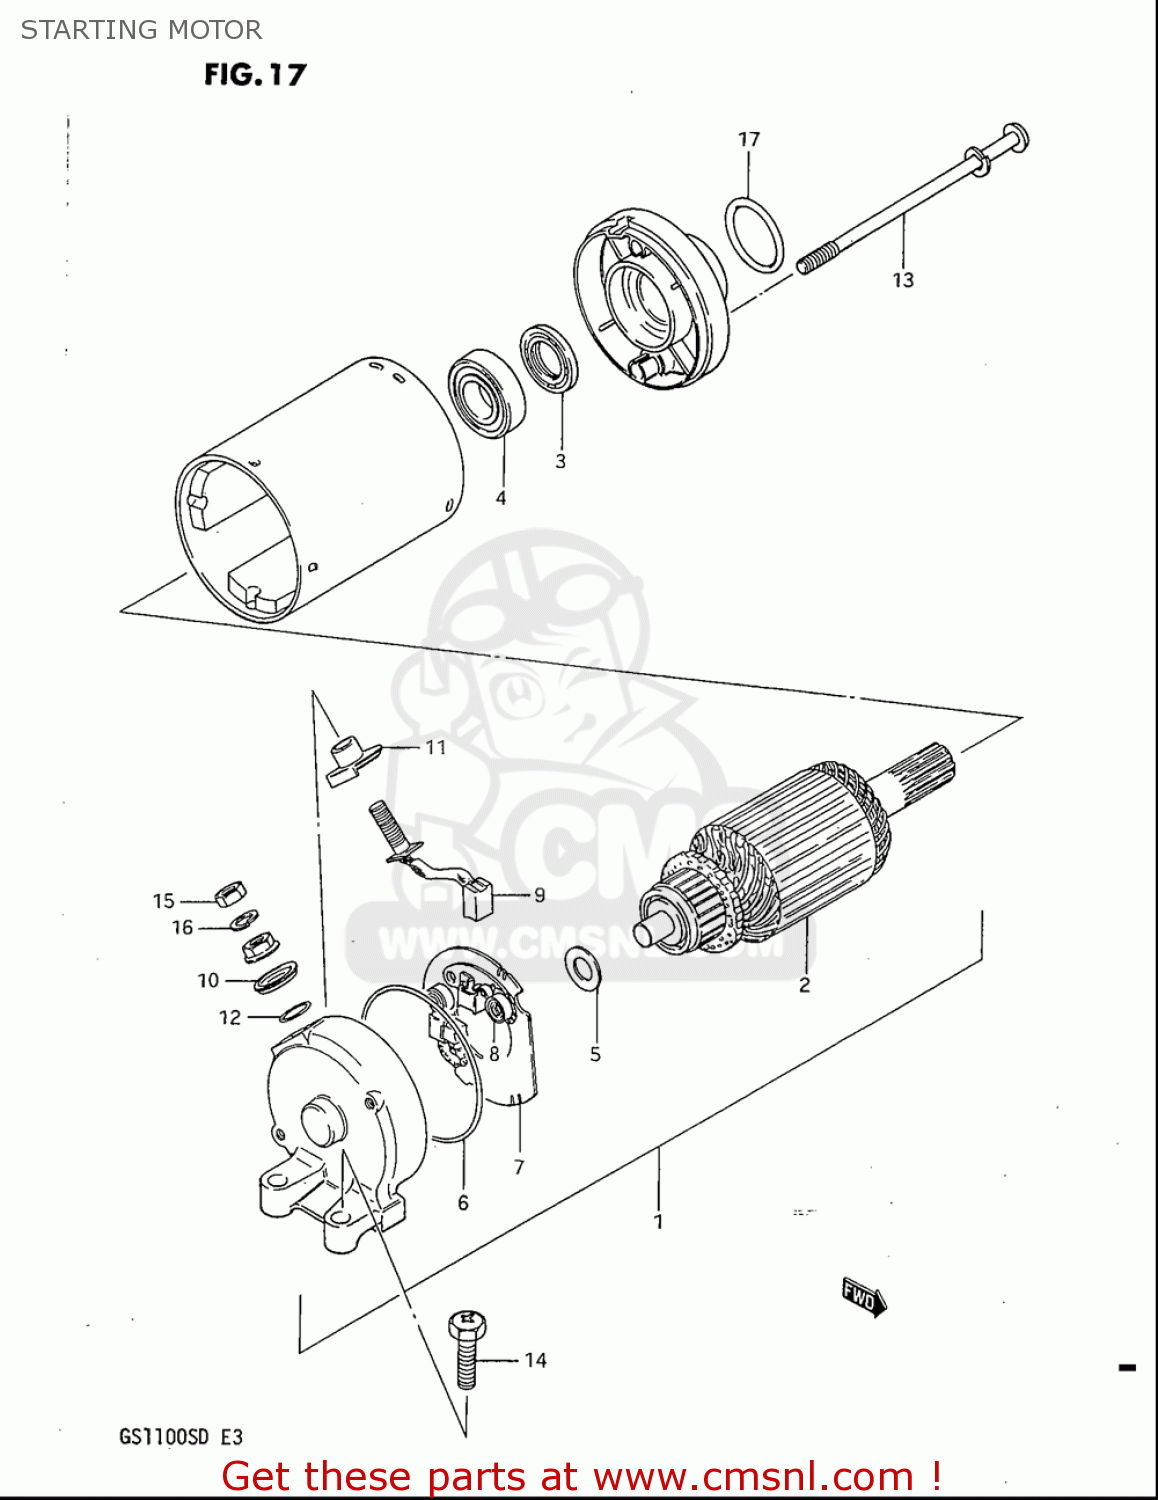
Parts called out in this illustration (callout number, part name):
1	MOTOR ASSY,STARTING
2	ARMATURE
3	SEAL,OIL
4	BEARING
5	SHIM SET,STARTING MOTOR
6	O RING
7	HOLDER,BRUSH
8	SPRING
9	BRUSH SUB ASSY,STARTING MOTOR
10	BUSHING (1)
11	BUSH,NO.2
12	O-RING
13	BOLT
14	SCREW (6X25)
15	NUT
16	WASHER,LOCK
17	O RING(D:2,ID:24.5)
